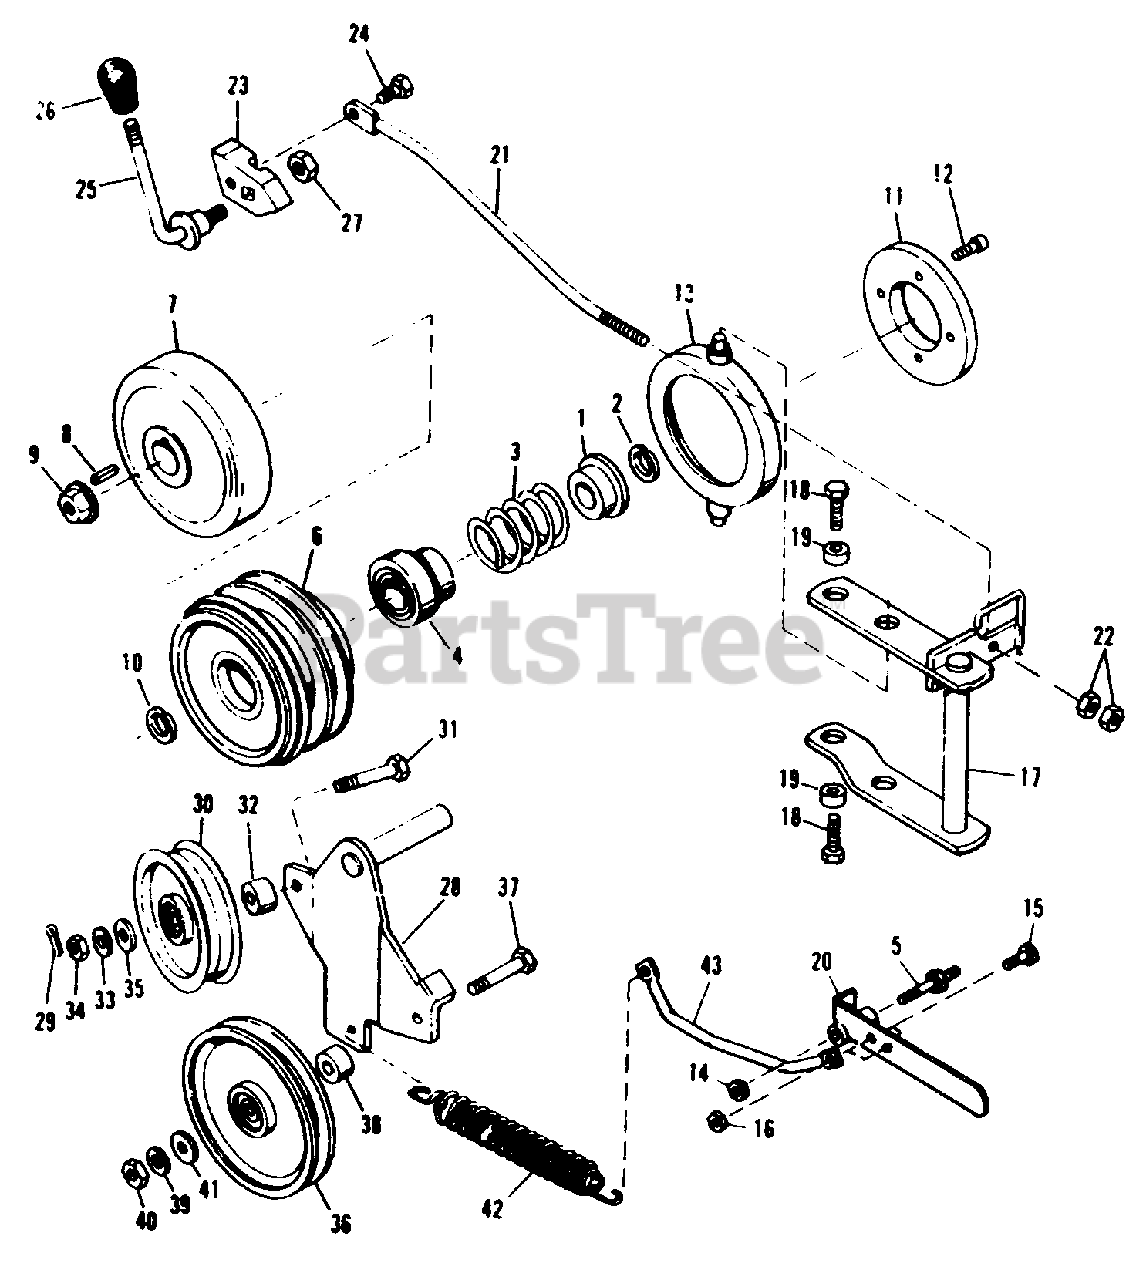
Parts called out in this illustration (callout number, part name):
1	Inner Spring Guide
2	Ring, Retaining
4	Bushing Assembly
7	Clutch Plate Assy.
9	Washer Base Lock Nuts
10	Ring, Retaining
12	Socket Hd. Screw, 1/4"-20 x 5/8"
13	Support Brake Assy.
14	Hex Lock Nut, Full, 7/16"-14
15	Hex Cap Screw, 5/16"-18 x 3/4"
16	Hex Lock Nut, Full, 5/16"-18
17	Pivot Assy.
18	Thread Forming Screw, 5/16" x 18x 1" lg.
20	Handle Assy.
21	Control Rod
22	Hex Nut Full, 5/16"-18
24	Special Cap Screw, 5/16" UNC-2A x 7/8" Grade 5
25	Handle, Clutch PTO
26	Knob
27	Hex Lock Nut, Full, 3/8"-16
28	Pivot Arm Assy.
29	Cotter Pin, 3/16" x 1-1/2"
31	Hex Cap Screw, 3/8"-16 x 2"
33	Lock Washer, 3/8"
34	Hex Nut, Full, 3/8"-16
35	Plain Washer, 5/16"
36	Idler Pulley
37	Hex Cap Screw, 3/8"-16 x 2"
39	Lock Washer, 3/8"
40	Hex Nut, Full, 3/8"-16
41	Plain Washer, 5/16"
42	Spring Tension
43	Spring Tension Rod
